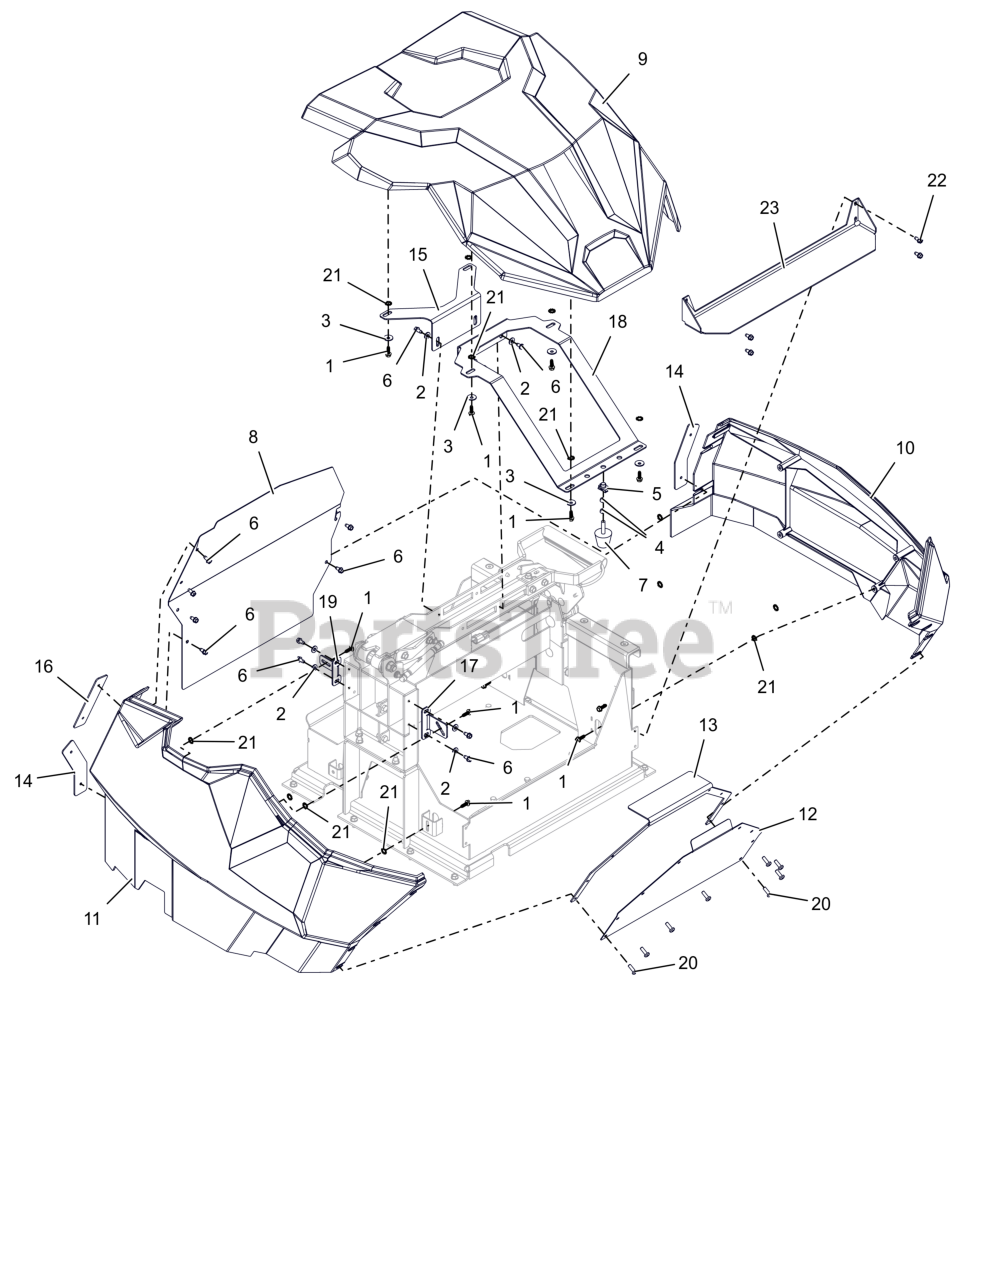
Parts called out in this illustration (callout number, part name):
1	SCR, PLASTITE-HWH 0.25 X 0.75 ZC120
2	WSHR,FLT .281X.625X.065 ZCC
3	WSHR, BLVL - .250 X .815 X .061 ZFS
4	NUT-JAM .312-18 G2 ZCC
5	NUT-CLIP RETAINER 5/16-18X.56
6	SCR-TAP .25-20X.50 HWH ZCC
7	BUMPER,STUD MOUNTED CONE SHAPE
8	BRKT, FENDER - REAR (BLACK)
9	HOOD, BATTERY CAPTURE
10	FENDER, BATTERY CAPTURE - LH
11	FENDER, BATTERY CAPTURE - RH
12	BRKT, FENDER - FRONT (RED)
13	PLATE, BACK - FRONT (BLACK)
14	PLATE, BACK REAR LH (BLACK)
15	SUPPORT, HOOD (BLACK)
16	PLATE, BACK - REAR UPPER (BLACK)
17	SUPPORT, FENDER (BLACK)
18	SUPPORT, HOOD (BLACK)
19	SUPPORT, FENDER (BLACK)
20	SCR-TAP 1/4-20X3/4 LPAN TL BZ
21	WSHR-LK-EXT 0.326X0.599X0.031 ZCC
22	SCR-TAP .25X.50 HWH ZB500
23	BRKT, STORAGE (RED)
